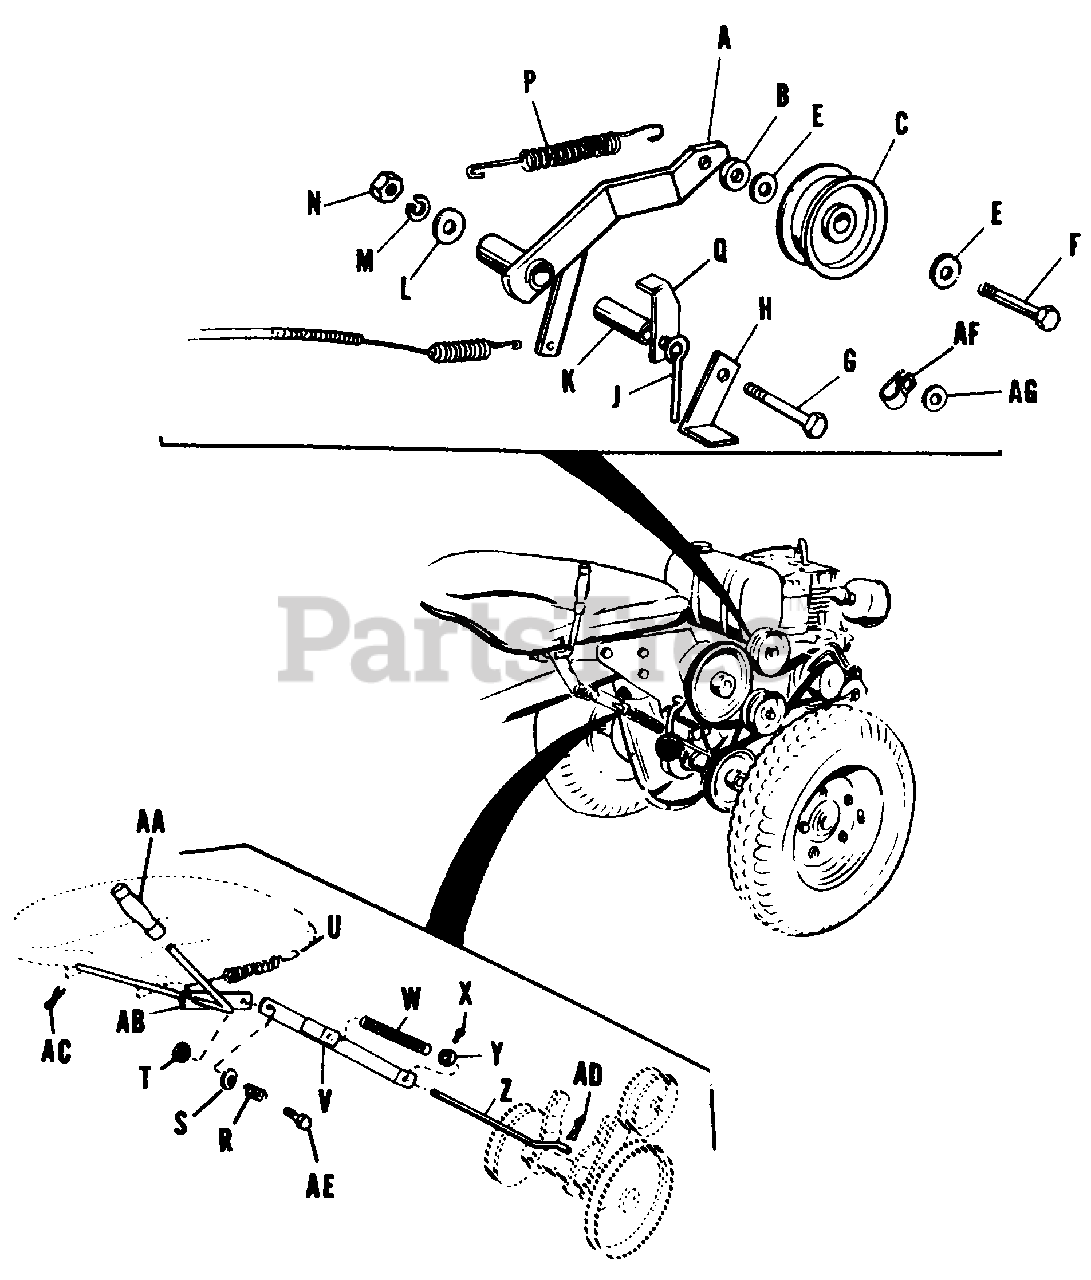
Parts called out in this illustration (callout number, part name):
A	Idler Lever Assembly
C	Idler Pulley
E	Washer, Plain, 5/16
F	Capscrew, Hex Hd., 3/8 x 1 1/2
G	Capscrew, Hex Hd., 3/8 x 3
H	Guide, Belt
J	Pin, Lock
K	Spacer, Idler Lever
L	Washer, Plain, 3/8
M	Washer, Lock 3/8
N	Nut, Hex, Full, 3/8
P	Spring, Idler Lever
Q	Stop, Lever
S	Washer, Plain, 5/16
T	Nut, Lock, Full Hex, 3/8-16
V	Guide Assembly, Clutch Rod
X	Set Screw, Sq. Hd., 1/4 x 3/8
Z	Rod, P.T.O. Clutch
AB	Lever Assembly, Clutch
AC	Cotter Pin, 1/8 x 1
AD	Cotter Pin, 3/32 x 5/8
AE	Capscrew, Hex Hd., 3/8 x 1 1/4
AG	Washer, Plain, 3/8
